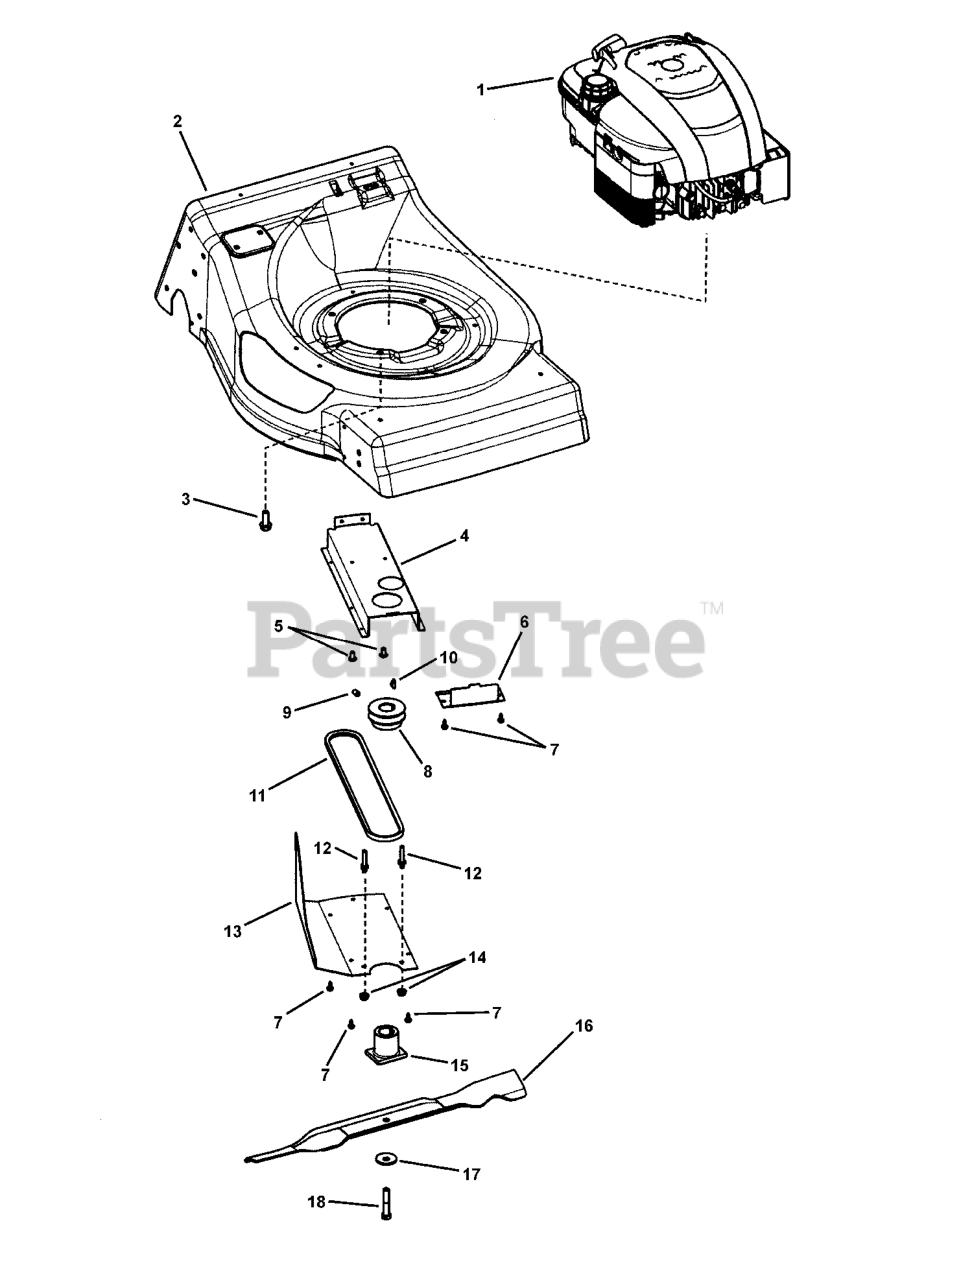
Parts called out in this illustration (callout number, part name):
2	DECK, 21" BRUTE, RD
3	BOLT, 3/8-16 X 1
4	BELT GUARD
5	PHST, 1/4-20 X 1/2 TORX
6	COVER, BELT
7	SCREW, #10X1/2, AB, W/WASHER
8	PULLEY, ENGINE
9	HRSS 5/16-18X1/2
10	KEY, #HP-506 HI-PRO
11	BELT, 3L, TRACTION DRIVE, 21" PIVOT HANDLE
12	BELT GUIDE, ENGINE, 21" RD (1/4-20 thread)
13	COVER, BELT GUARD
14	NUT, 1/4 X 20 YZ
15	HUB, BLADE, 21" WBM, RD, 2 POSITION
16	BLADE, WAVE, 21" STEEL DECK
17	WASHER, CONE
18	CAPSCREW, 3/8-24 X 2 GR5
